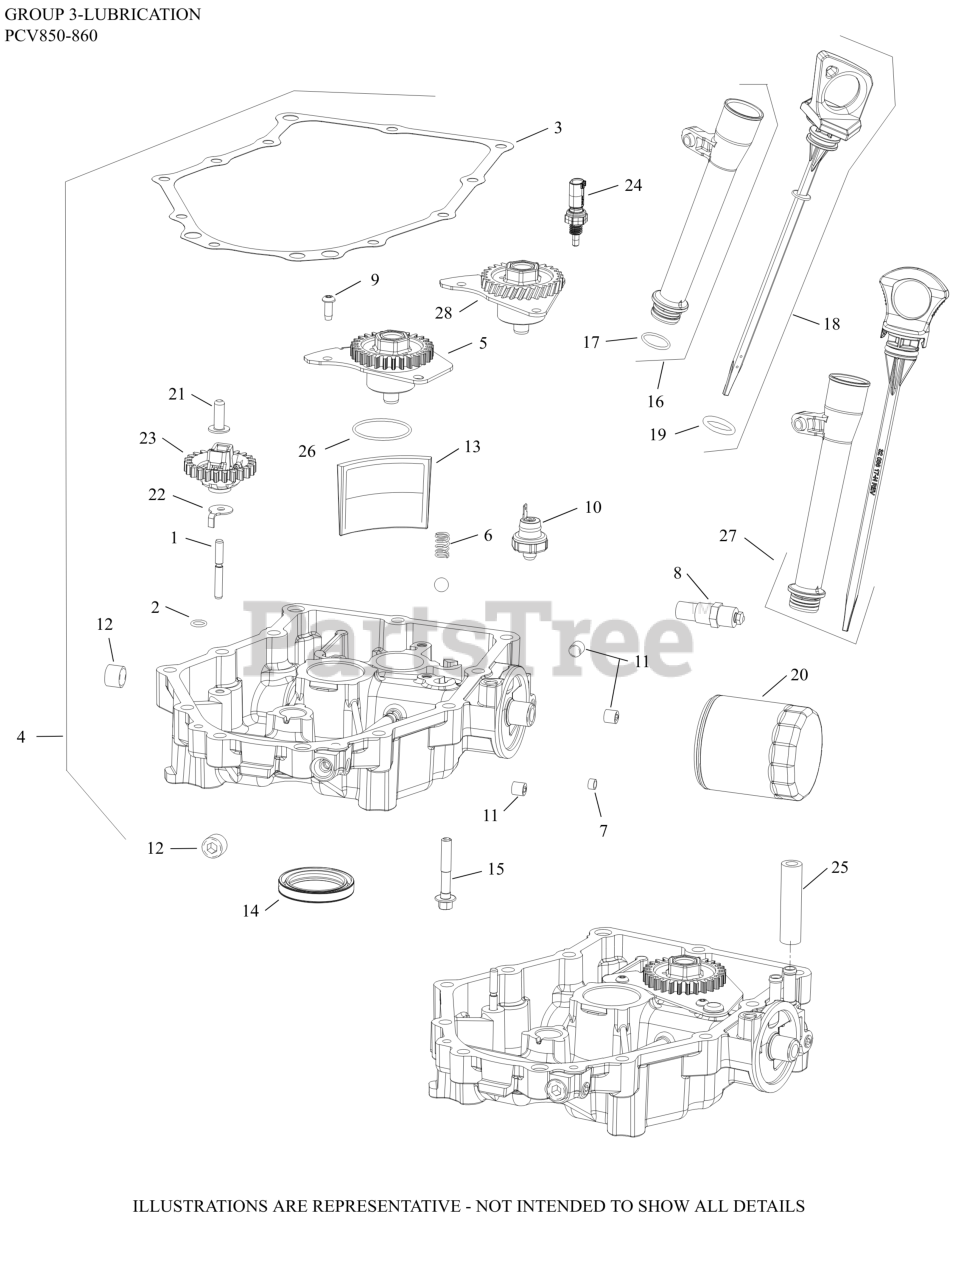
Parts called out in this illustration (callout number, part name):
1	SHAFT, GOVERNOR GEAR
2	O-RING (.5" DIA)
3	GASKET, OIL PAN
4	KIT, OIL PAN (MECH GOV-NO OIL COOLER)
4	KIT, OIL PAN (EGOV-NO OIL COOLER EXMARK)
4	KIT, OIL PAN (E-G0V-NO OIL COOLER)
5	PUMP ASSEMBLY, OIL
6	SPRING, COMPRESSION
7	PLUG, CUP
9	SCREW, BUTTON HEAD
10	SENSOR, OIL PSI
11	PLUG, CTSK PIPE 1/8"
12	PLUG, PIPE CTSK 3/8"
13	SCREEN, OIL
14	SEAL, OIL-(#2503218S)
15	SCREW, HEX FLANGE
20	OIL FILTER
24	SENSOR, TEMPERATURE
26	O-RING (1.78" DIA)
27	KIT, DIPSTICK AND TUBE WITH RINGS
